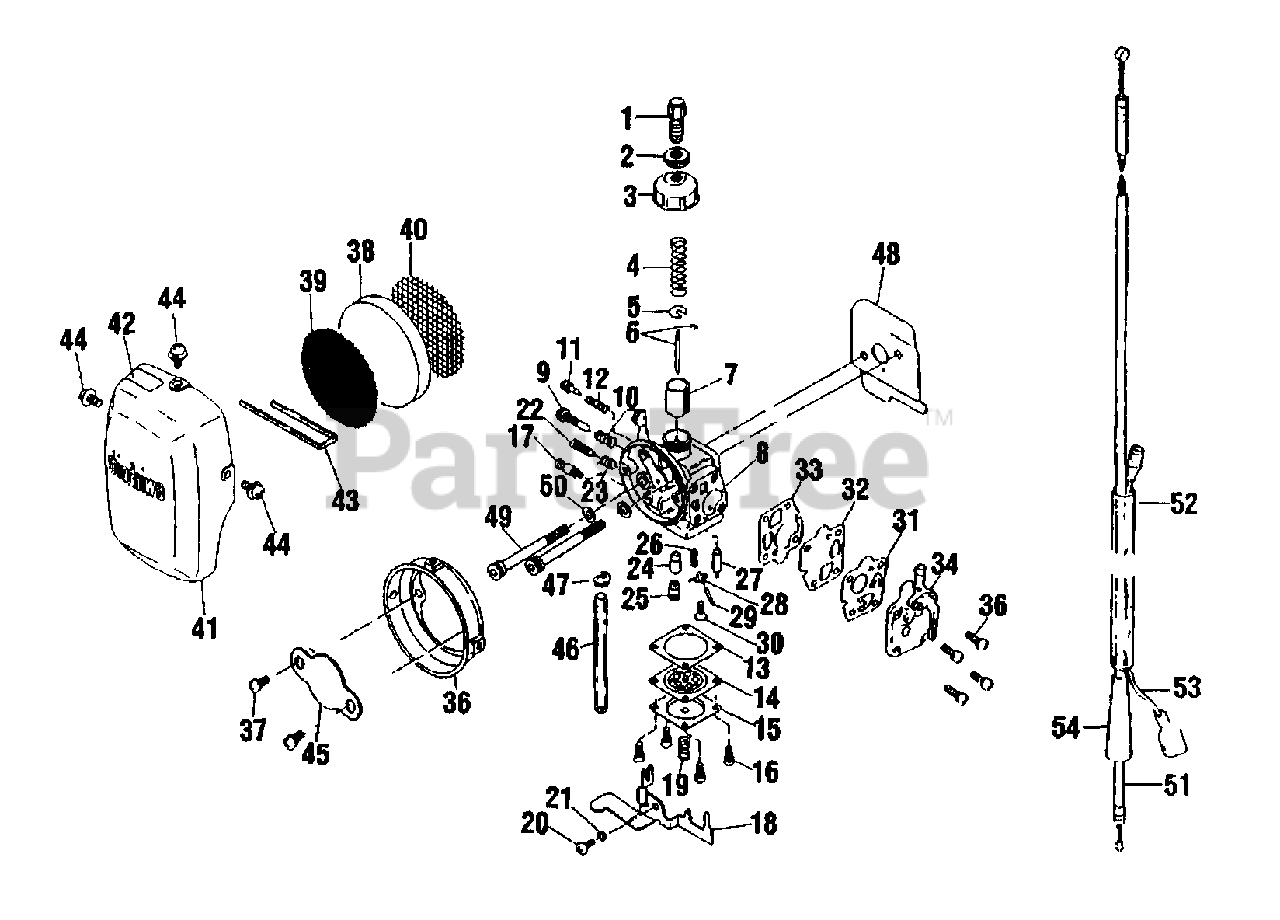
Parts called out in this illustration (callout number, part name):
1	NUT, CABLE ADJUST
2	LOCKNUT
3	CAP, CARBURETOR
4	SPRING
5	SPRING RECIEVE
6	NEEDLE
7	VALVE, THROTTLE
8	BODY, CARBURETOR
9	SCREW, IDLE ADJUST
10	SPRING
11	SCREW, SLOW AIR
12	SPRING
13	GASKET
14	DIAPHRAGM
15	COVER, METERING
16	SCREW
17	VALVE, OVERFLOW
18	LEVER, TICKLER
19	SPRING
20	SCREW
21	COLLAR
22	SCREW, ADJUST
23	SCREW, IDLE ADJUST
24	JET
25	HOLDER, JET
26	SPRING
27	VALVE, INLET NEEDLE
28	LEVER
29	PIN, METERING LEVER
30	SCREW, METERING LEVER PIN
31	VALVE, PUMP
32	DIAPHRAGM, METERING
32	DIAPHRAGM
33	GASKET, METERING
33	GASKET
34	BODY, PUMP
36	CASE, AIR FILTER
37	SCREW
38	FILTER, AIR - FOAM
39	SCREEN - OUTER
40	SCREEN - INNER
41	COVER, AIR FILTER
42	LABEL - CAUTION
43	CLIP
44	SCREW
45	PLATE
47	RING, RETAINING - 6
48	SHIELD, INTAKE
49	SCREW - 5X48
50	LOCKWASHER - 5
51	CABLE, THROTTLE
52	TUBE
53	LEAD - GROUND
54	CAP, DUST
